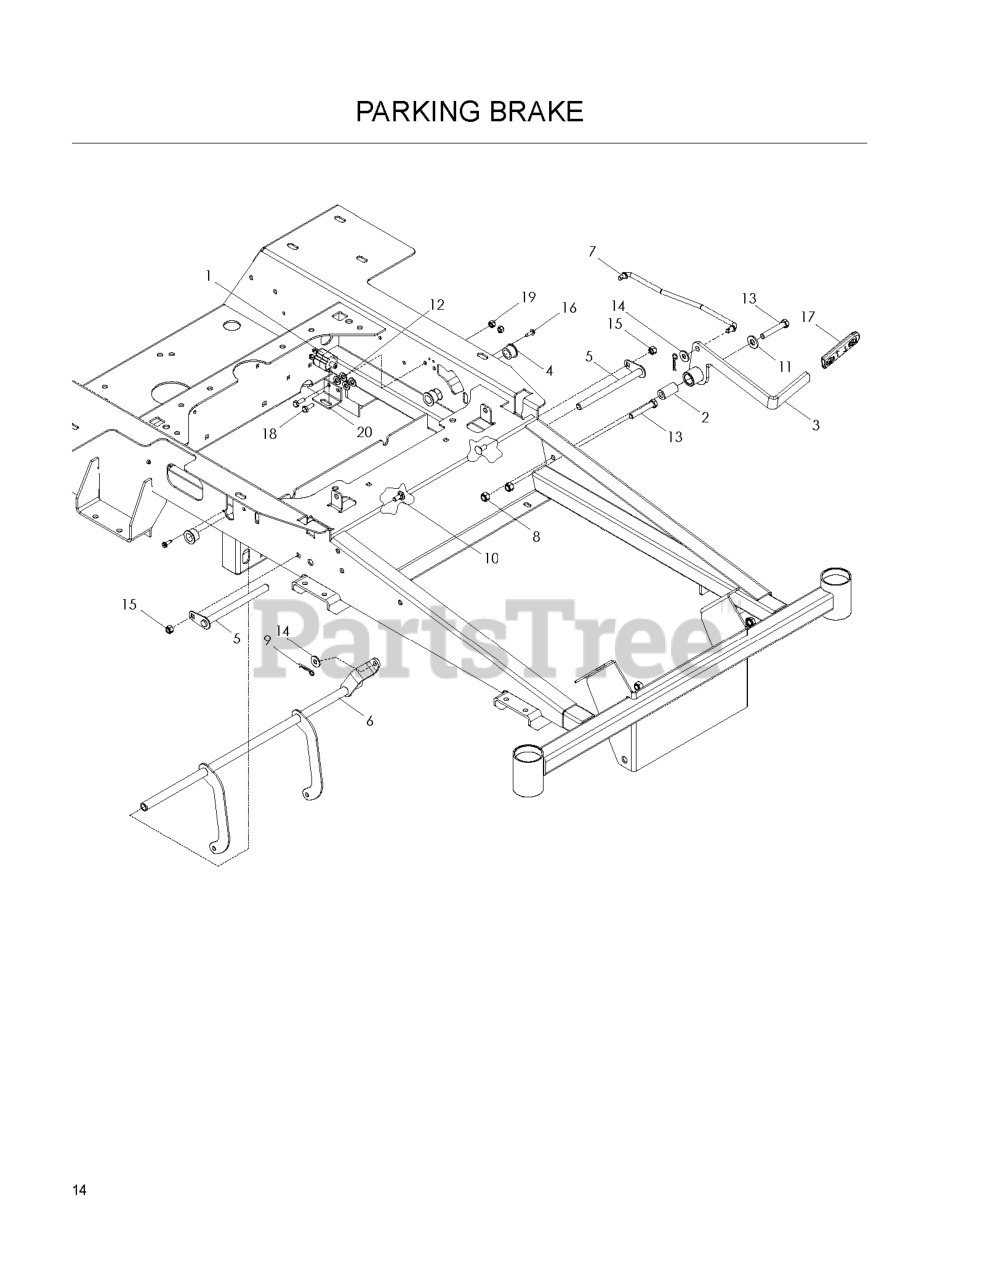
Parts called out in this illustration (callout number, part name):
1	SWITCH, BRAKE 3P
2	BUSHING, SLEEVE
3	BRAKE LEVER WLDMT
4	PLASTIC BUSHING
5	PIVOT SHAFT
6	BRAKE SHAFT
7	BRAKE LINKAGE
8	NUT 3/8-16 NYLOC
9	HAIRPIN #2
10	BOLT 5/16C X 3/4" CARRIAGE
11	WASHER 3/8 FLAT
12	FLAT WASHER 5/16 SAE
13	HCS 3/8C X 2 1/4
14	WASHER 5/16 FLAT
15	NUT 5/16 NYLOC
16	SCREW #10 X 1/2 SELF TAPPING
17	GRIP, PARK BRAKE
18	HCS 1/4C X 3/4 HCS
19	NUT.1/4-20.HEX.NYLOC.ZD
20	BRACKET, BRAKE SWITCH
